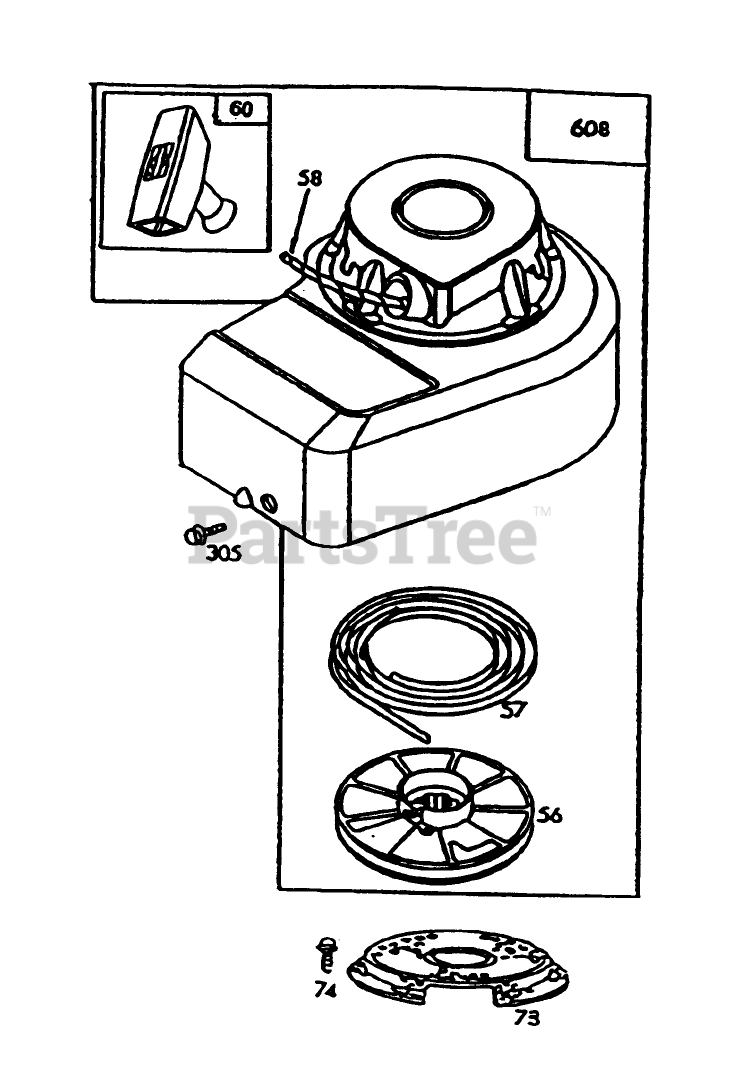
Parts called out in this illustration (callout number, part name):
56	Pully-Starter
57	Spring-Rewind
58	Insert-Starter Grip
60	Grip-Starter Rope
73	Screw-Sem
74	Screw-Sem
305	Screw-Blo. Hsg. Mtg.
608	Sorter Assy.-Rewind
